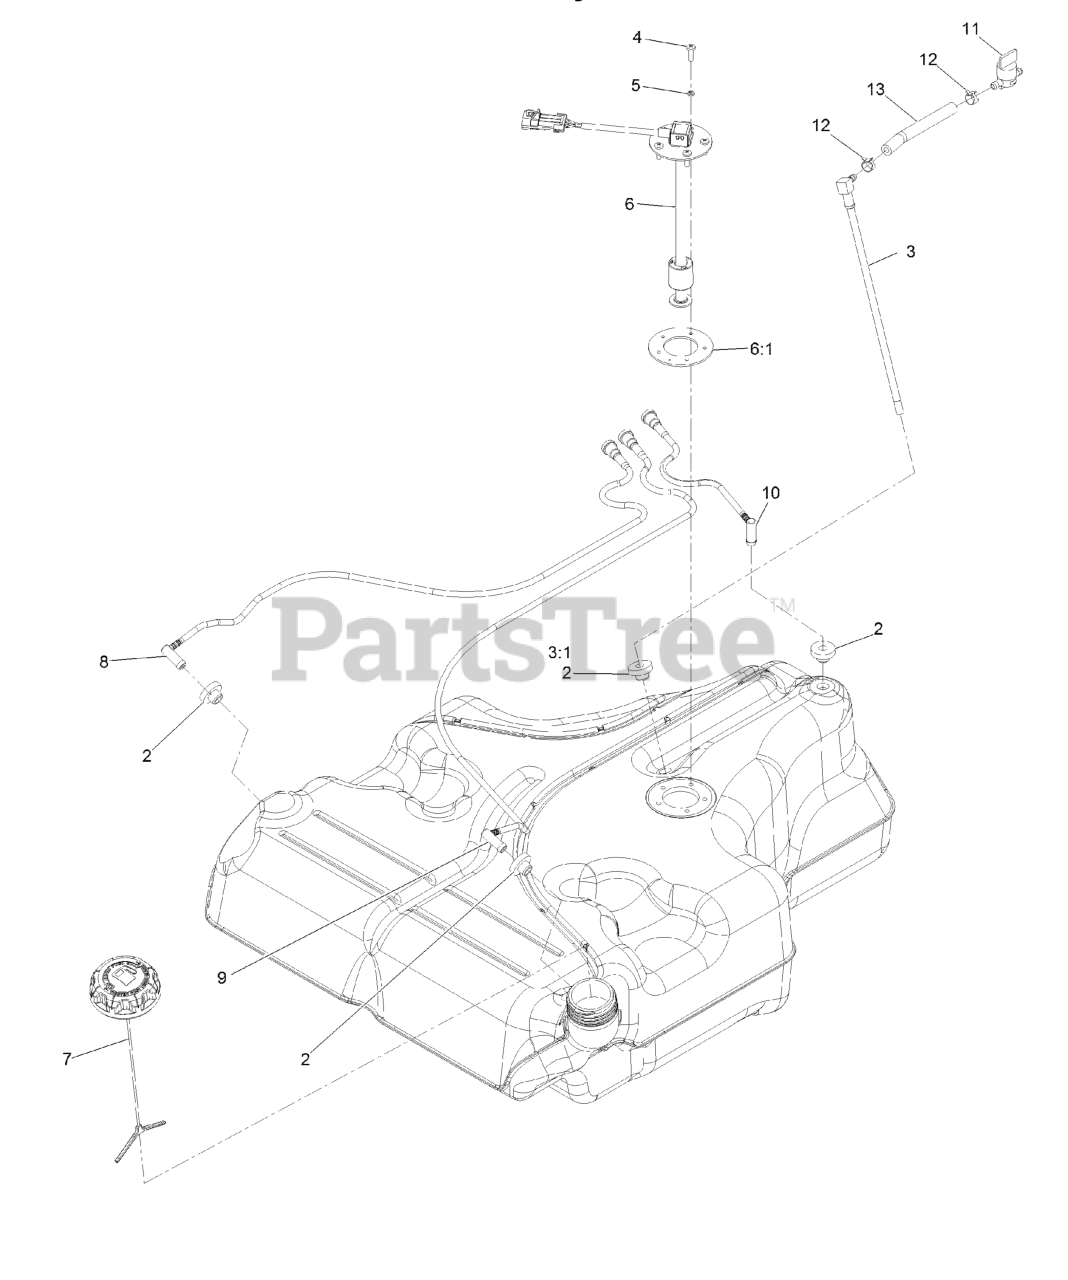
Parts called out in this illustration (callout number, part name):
2	BUSHING
3	FUEL LINE KIT (WITH GROMMET)
3:1	BUSHING
4	SCREW-PPH
5	WASHER-LOCK
6	FLOAT-SENDER, FUEL
6:1	Gasket-Sender
7	CAP-FUEL, RATCHETING
8	RH VENT LINE KIT (WITH GROMMET)
9	LH VENT LINE KIT (WITH GROMMET)
10	REAR VENT LINE KIT (WITH GROMMET)
11	VALVE-FUEL
12	CLAMP-HOSE
13	HOSE-FUEL
